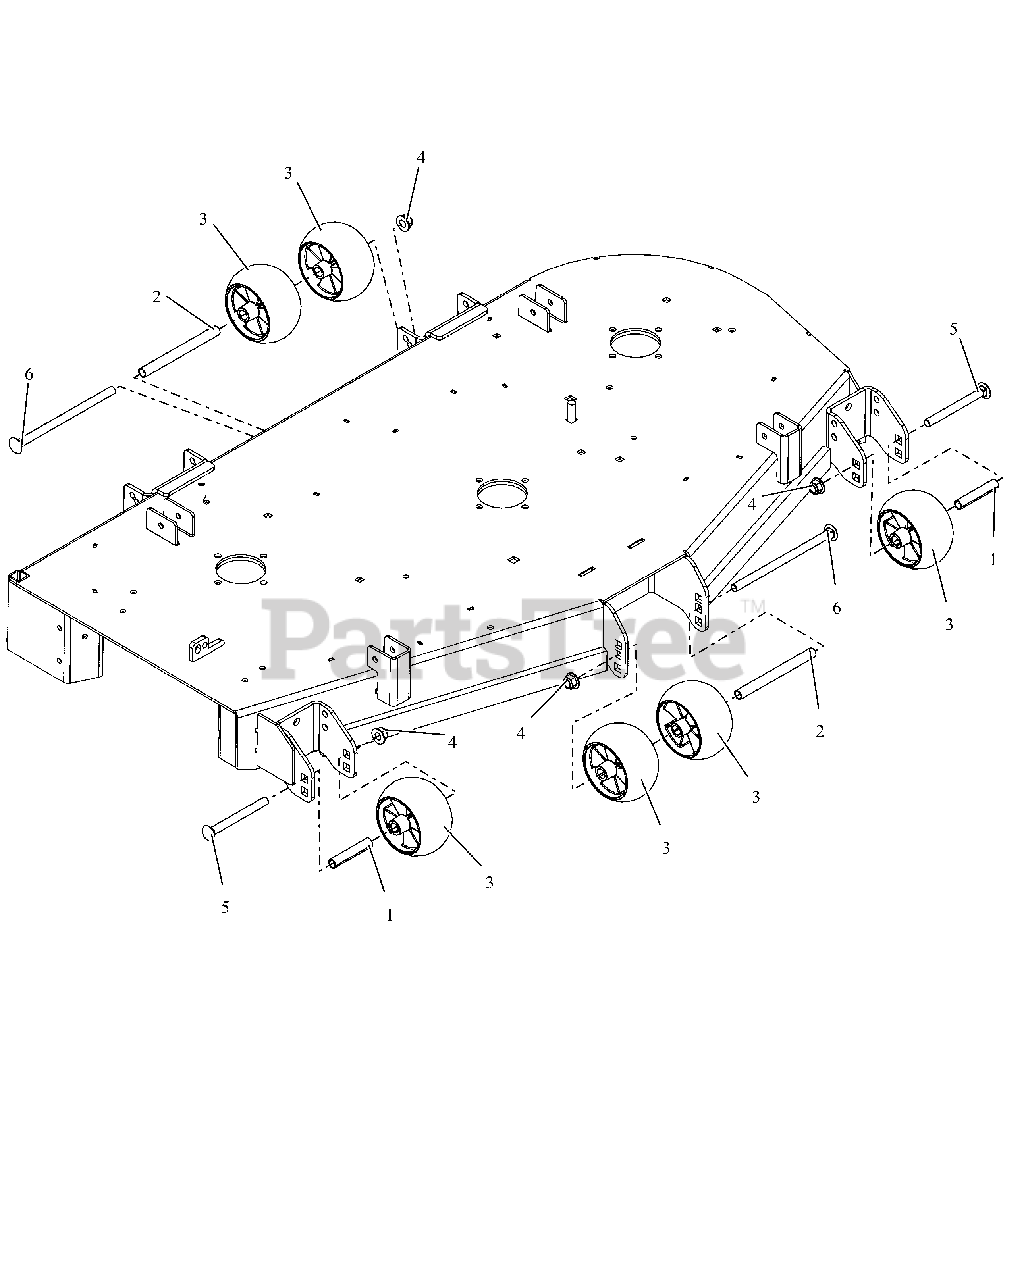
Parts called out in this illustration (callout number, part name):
1	SPACER, .510X.625X3.35
2	SPACER, .510X.625X6.50
3	ANTI-SCALP WHEEL - 5X3 CTR
4	NUT,NYL-FLG .50-13 GF ZCC
5	BLT, RHSN .50-13X5.00 G5 ZCC
6	BLT, RHSN .50-13X8.50 G5 ZCC
